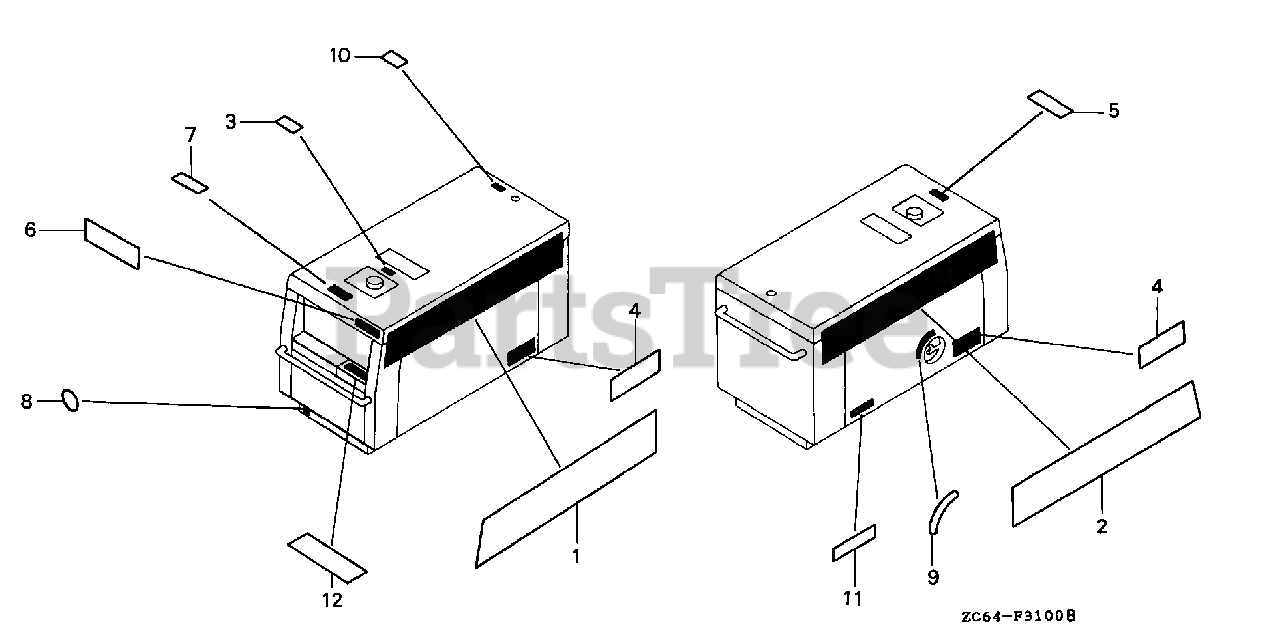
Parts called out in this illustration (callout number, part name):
1	MARK, R. STRIPE EMBLEM
2	MARK, L. STRIPE EMBLEM
3	MARK, FUEL WARNING (A)
4	MARK, SIDE EMBLEM (EB12D)
5	LABEL, RAIN WARNING (ENGLISH)
6	MARK, FR. EMBLEM
7	LABEL, OPERATOR WARNING (A)
8	MARK, GROUND
9	MARK, HANDLE INDICATION (E)
10	MARK, EX. CAUTION (A)
11	MARK, DRAIN INDICATION (E)
12	MARK, WARNING (GFCI)
